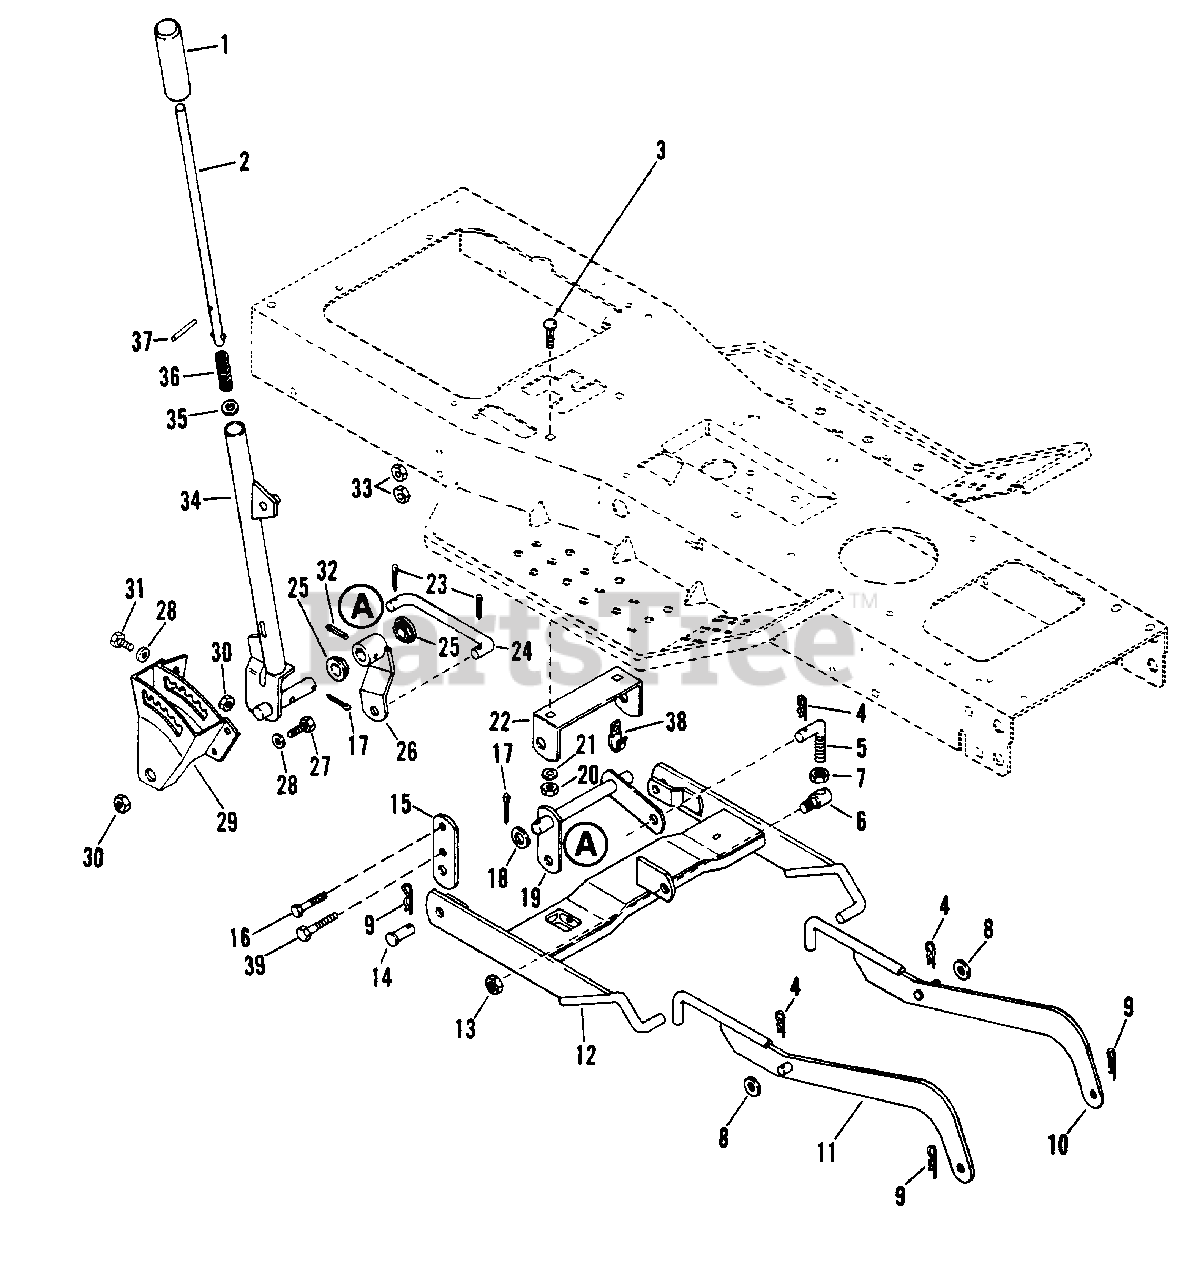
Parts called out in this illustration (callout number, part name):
1	GRIP
2	ROD, PLUNGER
3	BOLT, CARRIAGE 3/8-16X.75
4	HAIRPIN, INTERNAL
5	LINK, ADJUSTABLE
6	END, ROD
7	NUT, JAM 1/2-13 HEX
8	WASHER, FLAT .500X1.250X.083
9	HAIRPIN, INTERNAL
10	ARM, FRONT HANGER L.H.
11	HANGER, R.H.
12	HANGER, REAR
12	HANGER
13	NUT, LOCK 1/2-13
14	PIN, CLEVIS
15	BRACKET, HANGER
16	BOLT, HEX 3/8-16X.75
17	PIN, COTTER .125X1.500
18	WASHER, FLAT .813X1.37X.100
19	LEVER, CENTER LIFT
20	NUT, HEX 3/8-16
21	WASHER, LOCK 3/8 REG.
22	BRACKET, CENTER LIFT
23	PIN, COTTER .125X1.00
24	LINK, LIFT
25	BUSHING, FLANGE
26	ARM, LIFT
27	BOLT, HEX 5/16-18X1.25
28	WASHER, FLAT .312X.734X.065
29	QUADRANT, LIFT
30	NUT, LOCK 5/16-18
31	BOLT, HEX 5/16-18X.75
32	PIN, GROOVE 1/4
33	NUT, LOCK 3/8-16
34	HANDLE, LIFT
35	WASHER, FLAT .469X.938X.065
36	SPRING
37	PIN, SPRING .250X1.750
38	J-CLAMP
39	BOLT, HEX 3/8-16X1.00
